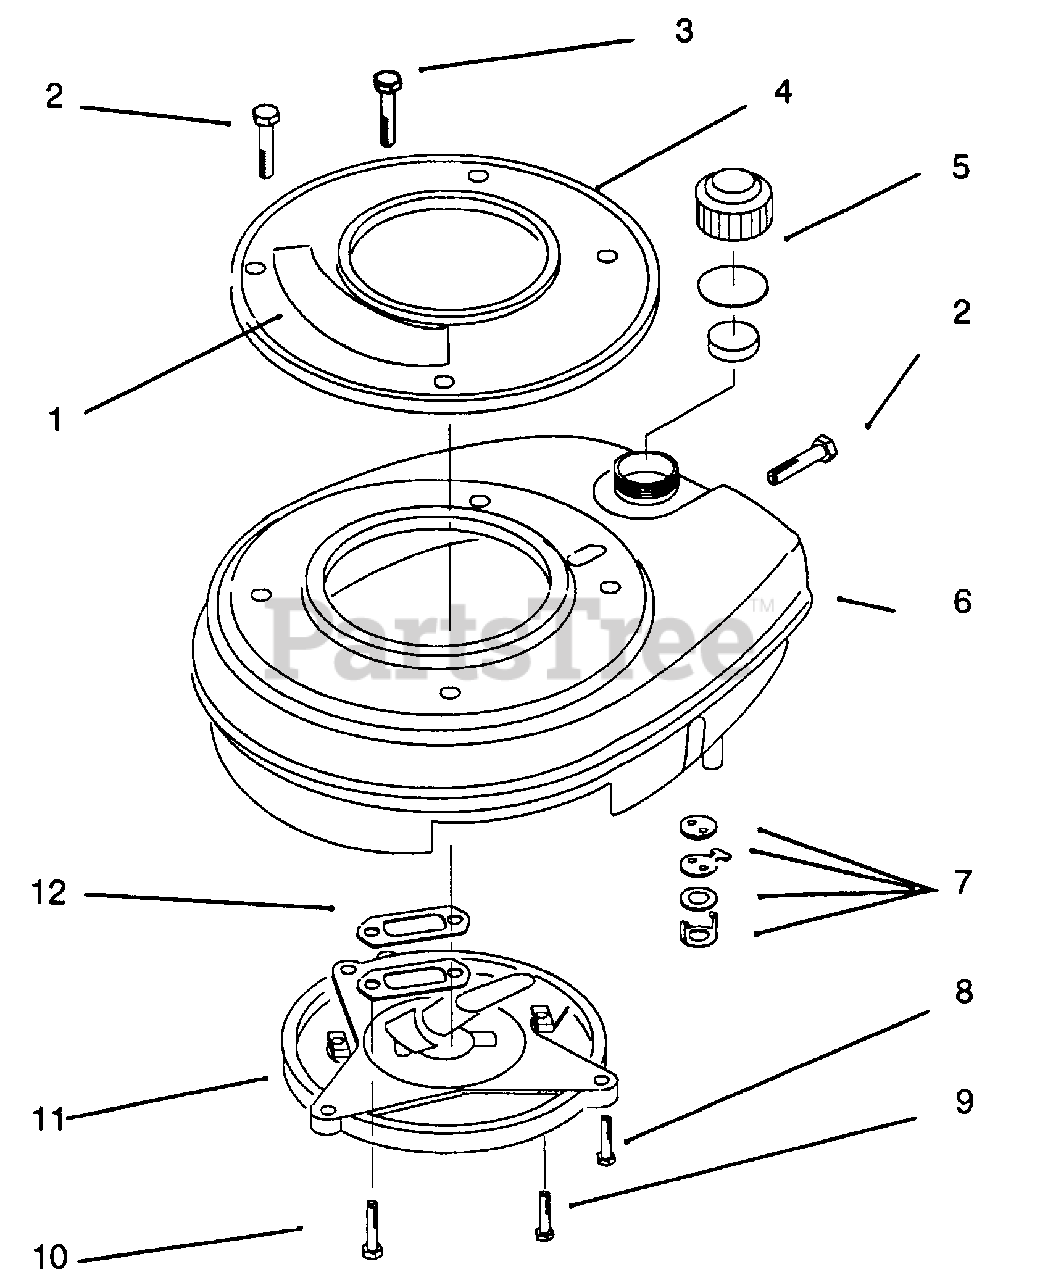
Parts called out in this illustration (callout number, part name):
1	Applique
2	Screw
3	Screw-Starter Mounting
4	Starter Base
5	Fuel Cap
6	Shroud-Engine
7	Fuel Shut-Off Assembly
8	Screw-Muffler Plt. to Hsg.
9	Screw-Muffler Plt. to Block
11	Plate-Muffler
12	Gasket-Exhaust
